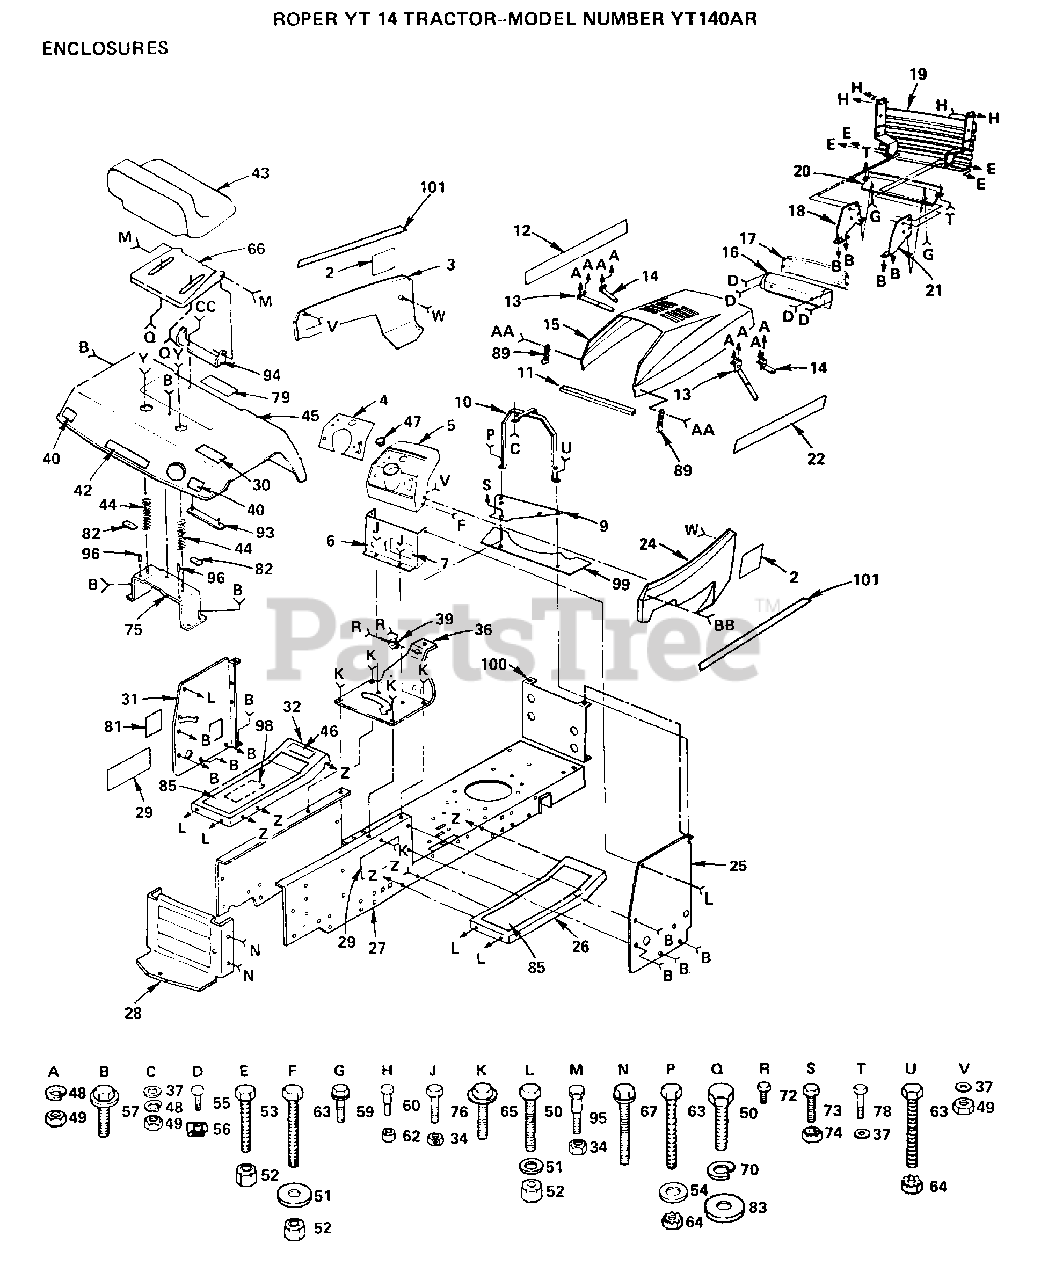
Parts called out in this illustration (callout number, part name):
6	LOWER DASH
11	FOAM-STRIP LT
17	LENS LT
18	SUPPORT-GRILL LT
30	DECAL-CAUTION
31	PANEL DASH HYT
37	WASHER PM
40	REFLECTOR-TAIL YT
47	PLUG-DASH T
51	WASHER
53	BOLT
54	WASHER
56	"""J"" FASTENER LT"
57	SCREW
59	SCREW
60	BOLT T
64	NUT
65	SCREW LT
67	SCREW
73	BOLT
78	SCREW HEX CRT
82	"CLAMP, SPRING LT"
83	WASHER
85	PAD FOOTREST T
89	SCREW
96	NUT-PUSH YT
